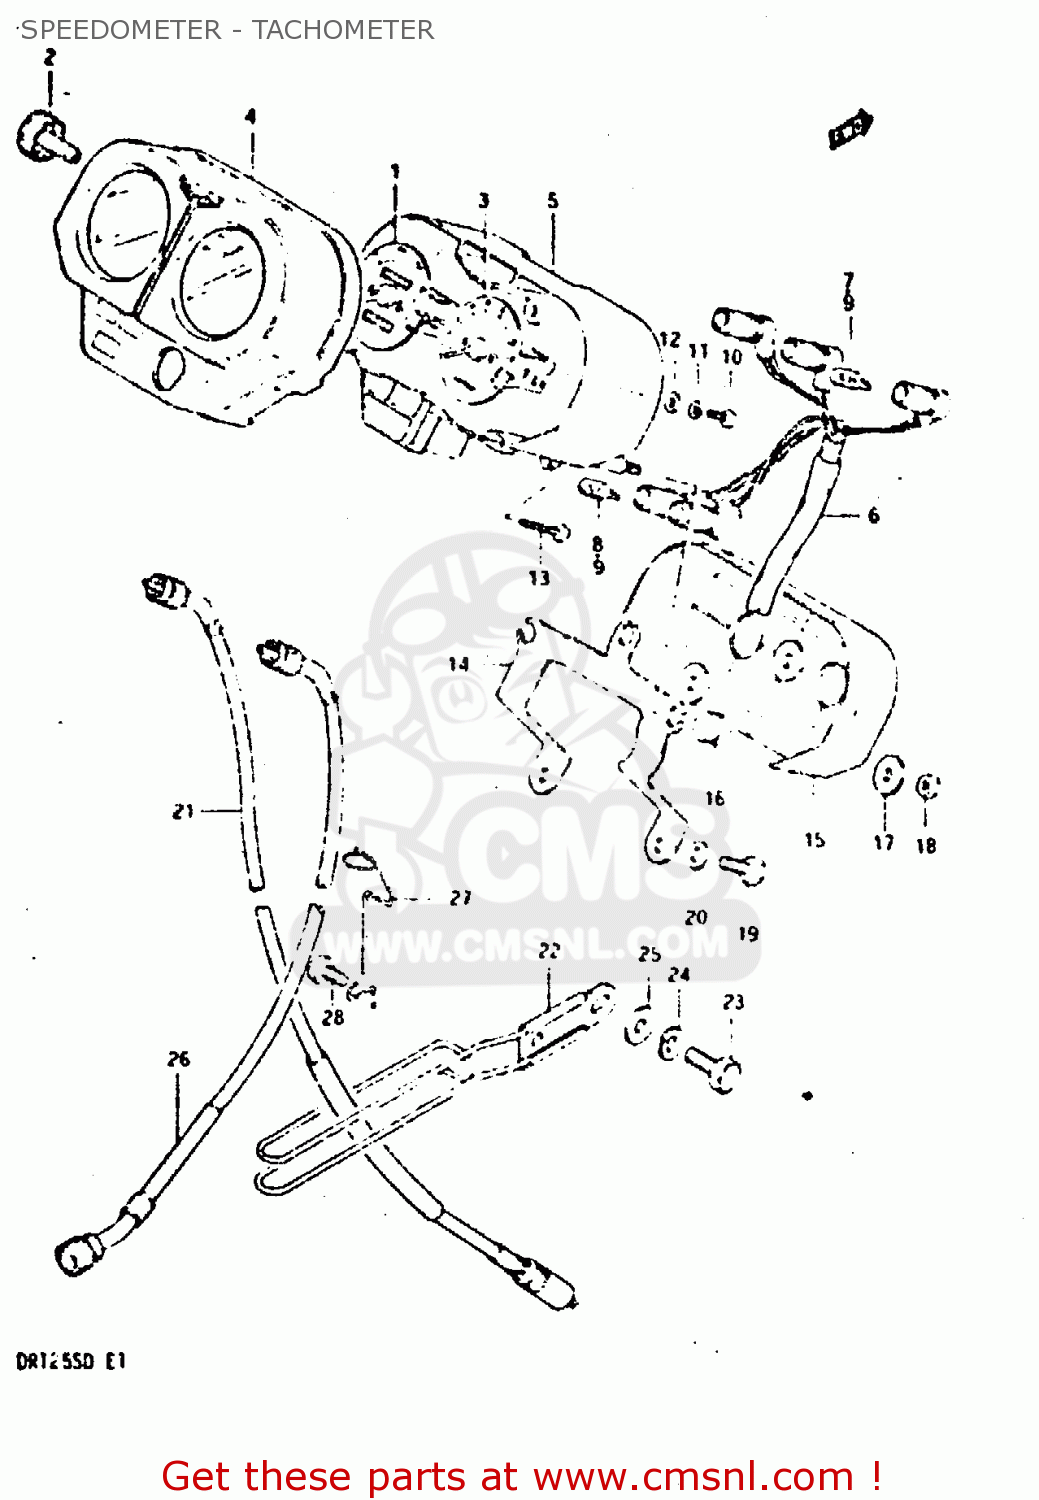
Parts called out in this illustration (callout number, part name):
1	SPEEDOMETER
2	KNOB,TRIP
3	TACHOMETER
4	HOOD, METER
5	CASE,INNER
6	SOCKET
9	BULB (7V,18/18W)
10	SCREW 4X10
11	LOCK WASHER
12	WASHER
13	SCREW
14	BRACKET,METER
15	COVER
16	CUSHION
17	WASHER (5.5X16X1.2)
18	NUT
19	BOLT
20	WASHER
21	CABLE ASSY,SPE
22	GUIDE,CABLE
23	BOLT 8X12
24	LOCK WASHER
25	WASHER
26	CABLE,TACHOMETER
27	GUIDE,TACHOMETER CABLE
28	SCREW, FRONT
